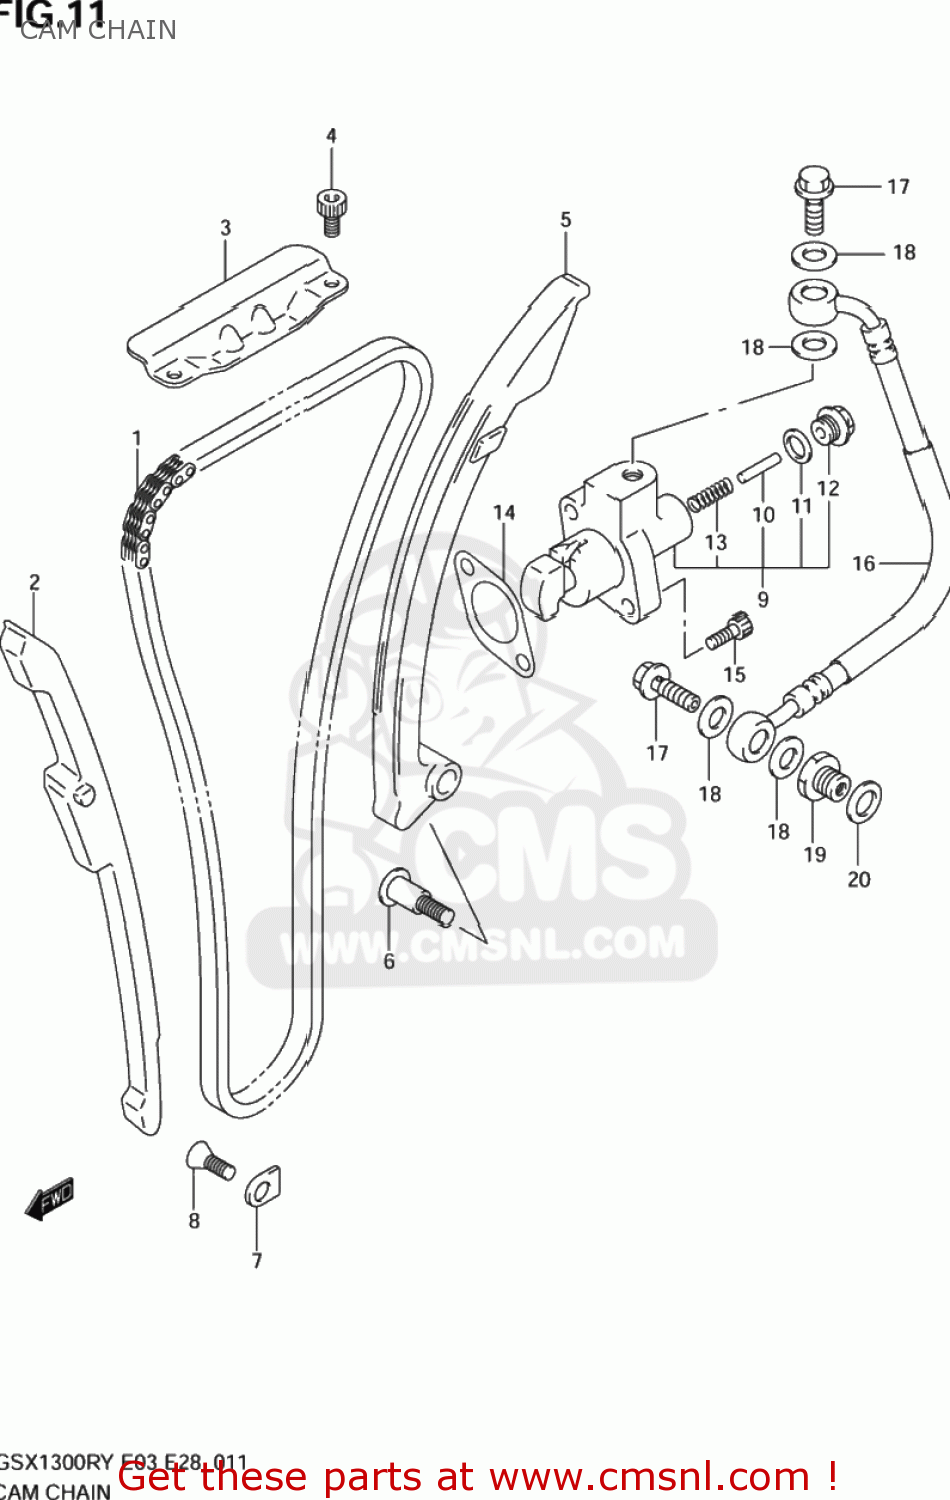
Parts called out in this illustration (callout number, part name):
1	CHAIN COMP,CAMSHAFT DRIVE
2	GUIDE,CAM CHAIN NO.1
3	GUIDE,CAM CHAIN NO.2
4	BOLT,STRANGER
5	TENSIONER,CHAI
6	BOLT,CAM CHAIN TENSIONER/GUIDE
7	RETAINER,CAM CHAIN GUIDE NO.1
8	SCREW
9	ADJUSTER SET,T
10	SHAFT,ADJUSTER
11	GASKET,TENSIONER ADJUSTER (NAS)
12	PLUG,FR TENSIONER ADJ
13	SPRING,MAIN
14	GASKET,TENSIONER ADJUSTER (NAS)
15	BOLT,CL.COVER
16	HOSE,CAM CHAIN TNSN ADJ OIL
17	BOLT,ADJUST OIL HOSE UNION
18	GASKET 8.2X14X1 (NAS)
19	PLUG,ADJ OIL HOSE UNION
20	GASKET(13.8X18.8X4.8) (NAS)
